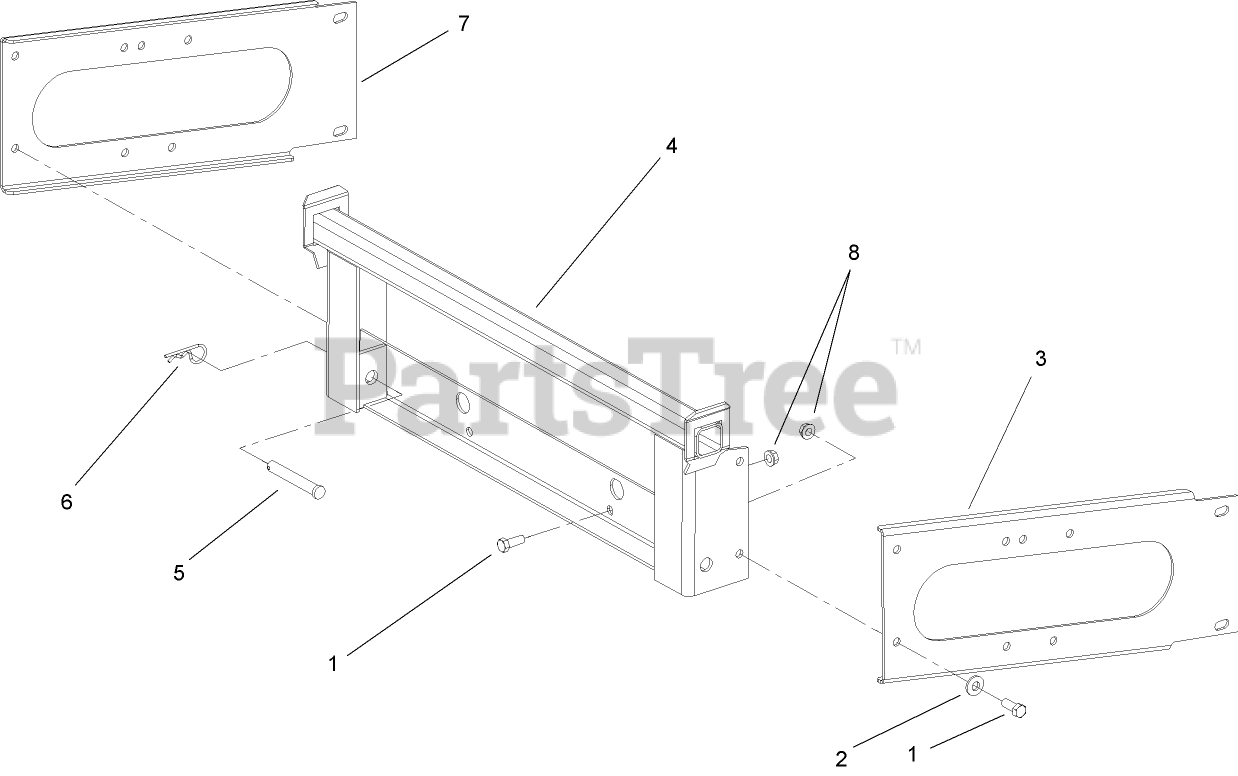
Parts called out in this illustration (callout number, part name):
1	SCREW-HH
2	WASHER-BELLEVILLE
3	BRACKET-FRAME, RH
4	MOUNT-BAGGER
5	PIN-CLEVIS
6	PIN-COTTER
7	BRACKET-FRAME, LH
8	NUT-HHF, WHIZ
